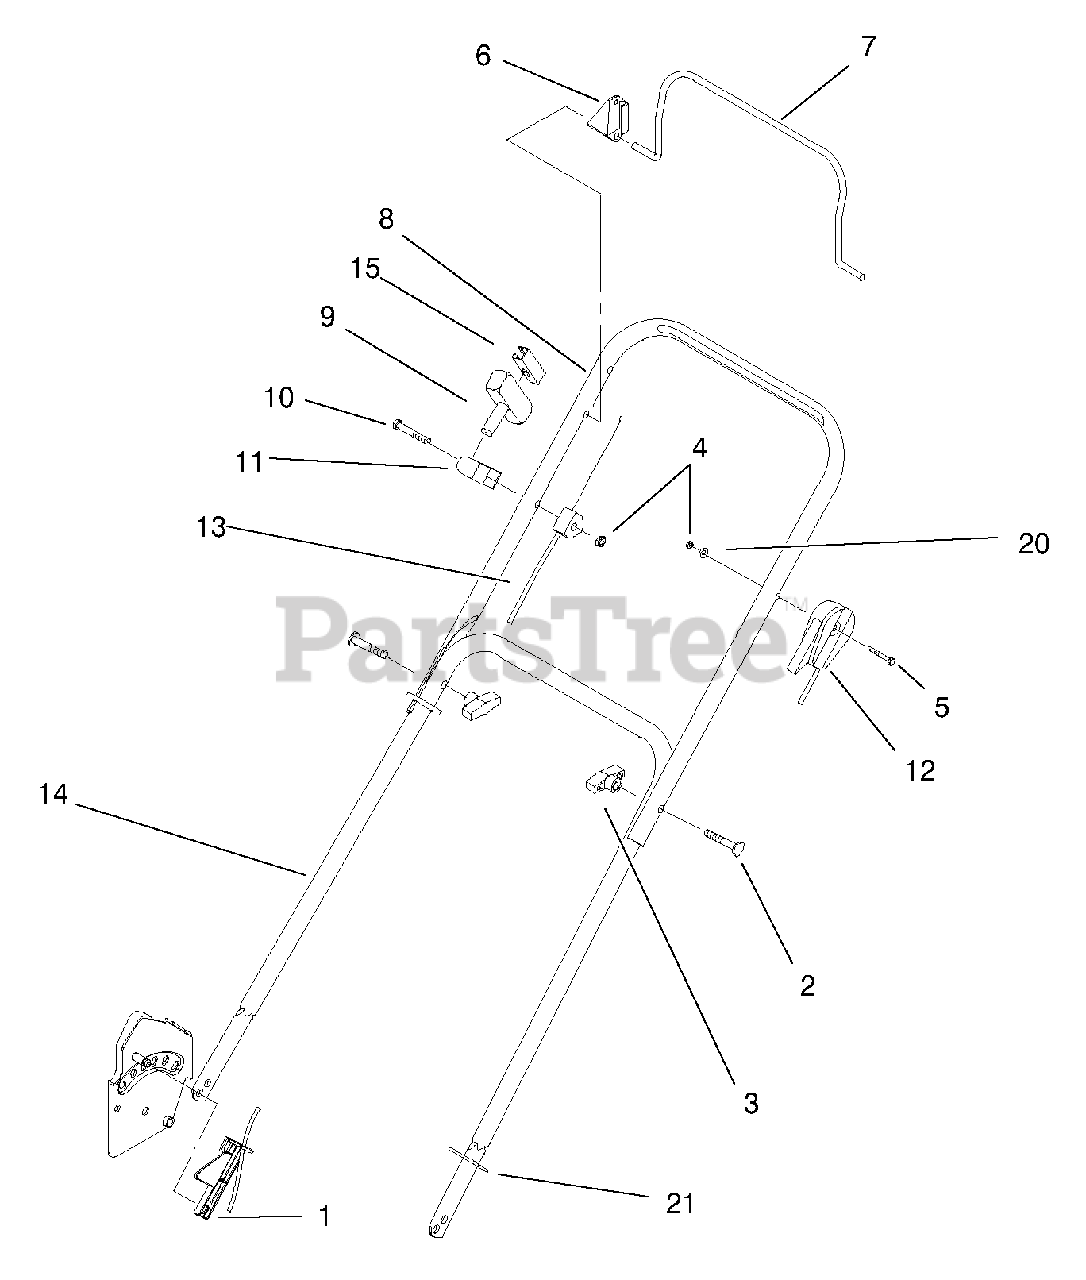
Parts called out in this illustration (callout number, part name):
1	GUARD-CABLE
3	KNOB-HANDLE
4	NUT-LOCK, NI
5	SCREW-HH
6	STOP-PIVOT
7	BAIL - BRAKE
8	HANDLE-UPPER
9	HANDLE-START
10	SCREW-HH
11	GUIDE-ROPE
12	CONTROL ASM - THROTTLE
13	CABLE ASM - BRAKE
14	HANDLE - LOWER
15	CLIP-STARTER
20	WASHER
21	TIE-STRAP
